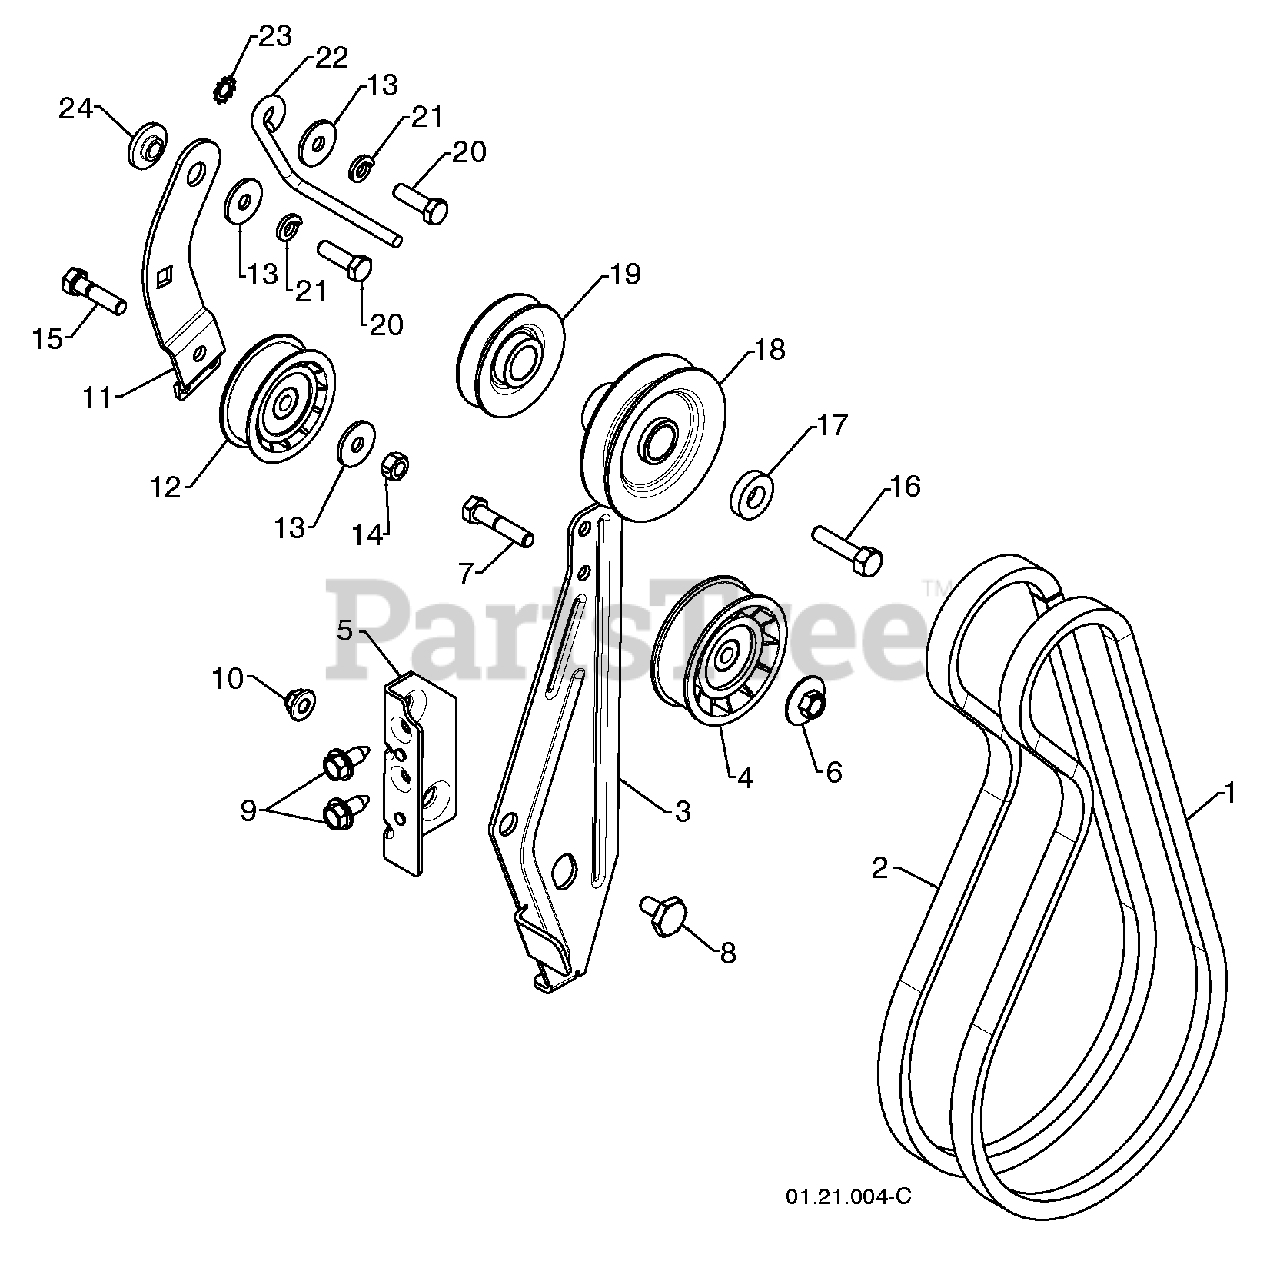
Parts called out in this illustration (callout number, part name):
1	IMPELLER BELT
2	TRACTION BELT
3	IDLER ARM BRACKET
4	IDLER PULLEY
5	IDLER ARM BRACKET
6	NUT 5/16-18
7	SCREW 5/16-18 X 1.50
8	SHOULDER BOLT 5/16-18 X .50
9	SCREW 5/16-18 X .750
10	NUT 5/16-18 NYLOCK
11	TRACTION IDLER BRACKET
12	TRACTION PULLEY
14	NUT 5/16-18
15	SCREW 5/16-18 X 1.25
16	SCREW 3/8-24 X 1.375
18	PULLEY ENG IMPELLER
19	PULLEY ENG TRACTION
20	SCREW 5/16-24 X 1.00
21	LOCKWASHER 5/16
22	BELT GUIDE
23	LOCKWASHER 5/16
24	IDLER BUSHING
